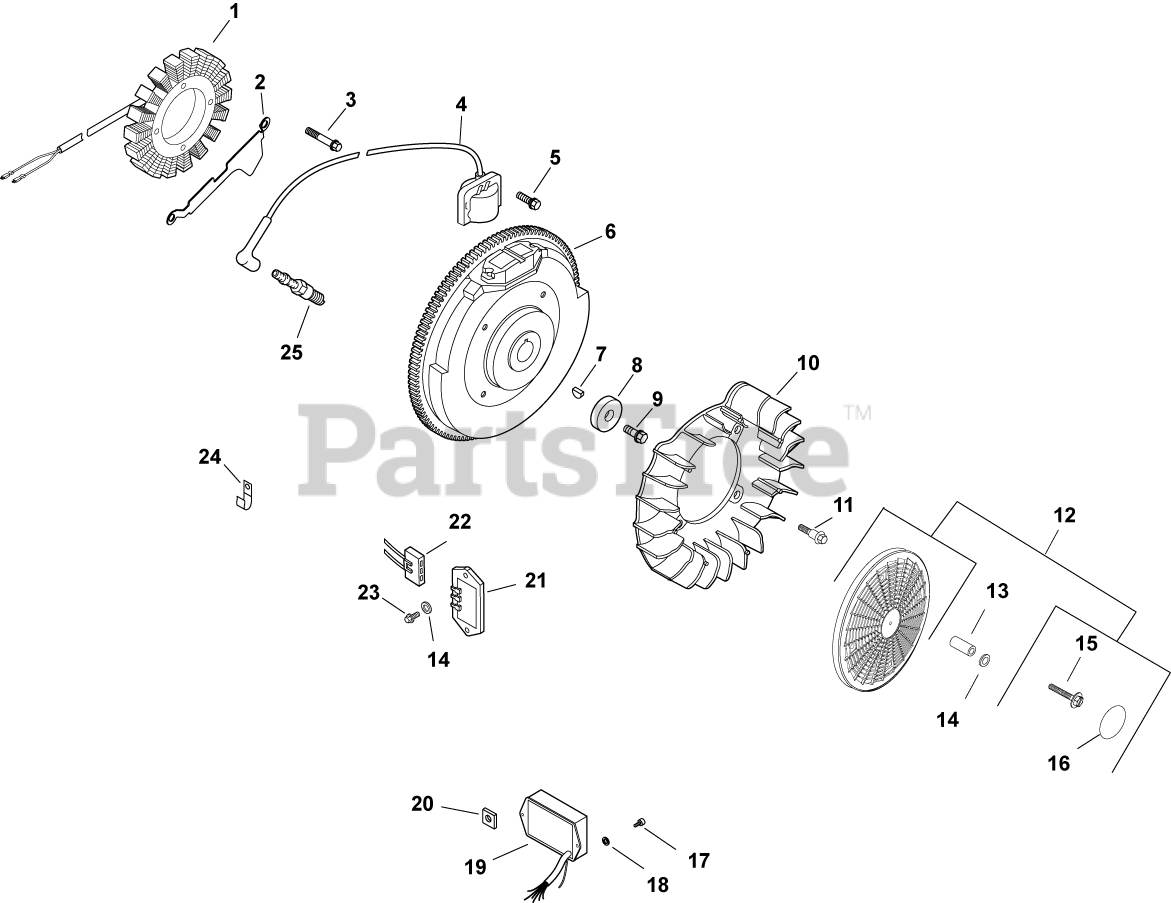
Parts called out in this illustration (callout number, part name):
1	KIT, 25 AMP STATOR ASSY.
2	BRACKET, STATOR WIRE
3	SCREW, M5X0.8X25 - (#25086402S)
4	MODULE, IGNITION
5	SCREW, SKT THD FRM M5X0.8X25
6	FLYWHEEL, PAINTED-USE 24 025 57-S
7	KEY, 3/16" X 5/8"
8	WASHER, FLAT 13/32"
9	SCREW, FLG M10X1.5X45 - (#25086361S)
10	FAN (WITH HOLE)-USE 24 157 16-S
11	BOLT, SHOULDER
12	KIT, GRASS SCREEN
13	SPACER - DISCONTINUED
14	WASHER, FLAT 3/16"
15	SCREW, SLT HD CAP M4X0.7X25
16	DECAL, GRASS SCREEN USE 24 113 499-S
17	SCREW, PHL HD #11-16X1/2"
18	WASHER, FLAT 1/4" (O.D. 1/2")
19	MODULE, SPEED ADVANCE-DISCONTINUED SEE PB265
20	NUT, PLASTIC
21	REG/RECTIFIER (20/25 AMP)-USE 25 403 20-
22	CONNECTOR, BODY (KM)-USE 25 155 41-S
23	SCREW, PHL HD #11-16X7/8"
24	CLIP, CABLE
25	PLUG, SPARK (PRO SERIES)
2545403-S	TIE, WIRE
24176112-S	HARNESS, WIRING-USE 24 176 150-S
X-22-11-S	WASHER, INT TOOTH LOCK 1/4"
